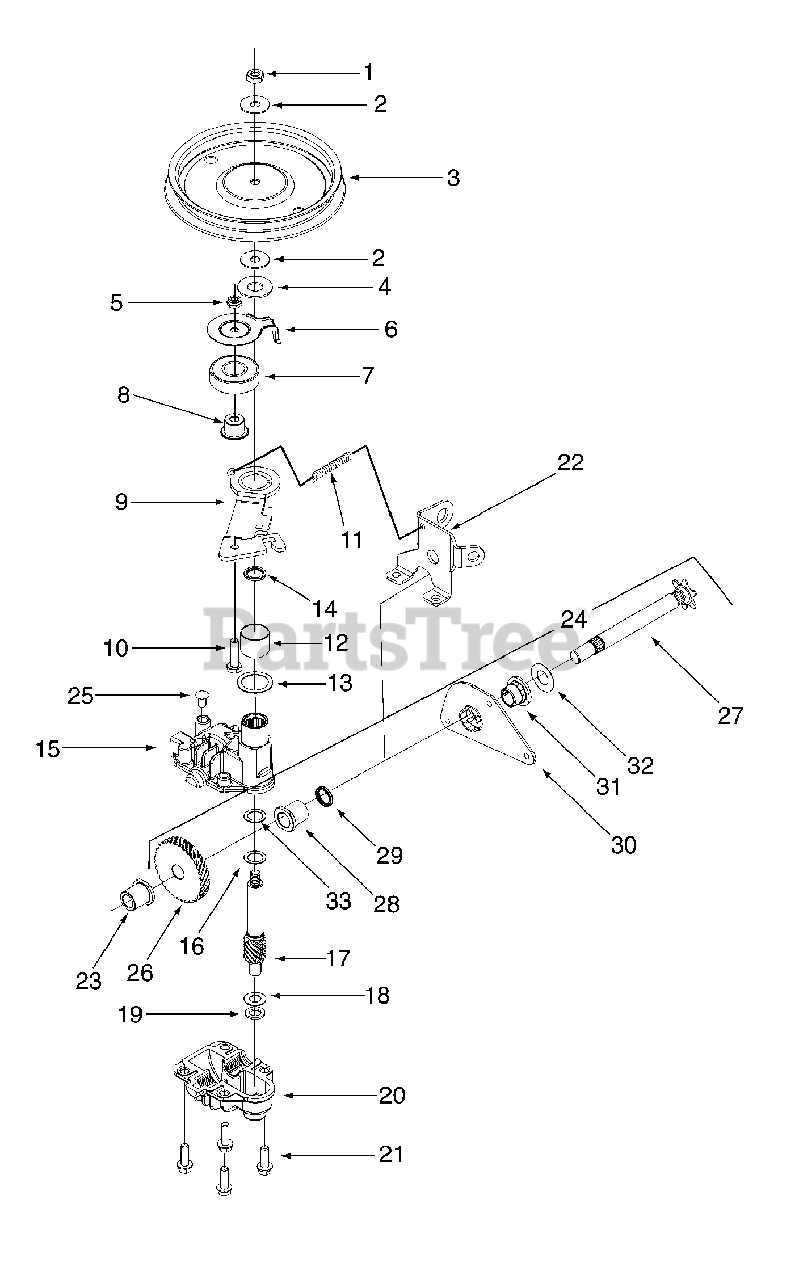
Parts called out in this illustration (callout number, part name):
1	Hx. Jam Nut 5/16-24
2	Bell Wash. .325 x .930 x .045
4	Fl. Wash. .510 x 1.120 x .060
5	Hx. Jam Nut 1/4-28
6	Belt Keeper
7	Bearing
8	Flange Spacer
9	Idler Bracket Assembly
10	Hx. Cap Scr. 1/4-28 x 1.00 Gr. 5
11	Extension Spring
12	Bearing Sleeve
13	Fl. Wash. .885 x 1.145 x.030
14	Oil Seal
15	Upper Housing Assembly
16	Thrust Wash. .504 x .700 x .030
17	Pinion Shaft 10 T.
18	Thr. Wash. 3/8 x .70 x .030
19	Thr. Wash. .388 x .625 x .062
20	Lower Housing Assembly
21	Hx. Scr. 1/2-20 x .75
24	Shaft Assembly
26	Gear 34 T.
27	Output Shaft 6 T.
28	Flange Bearing
29	Oil Seal
30	Pivot Bracket
31	Flange Bearing
32	Wash. Fl. .508 I.D. x 1.00 O..D. x.020
33	Bearing
